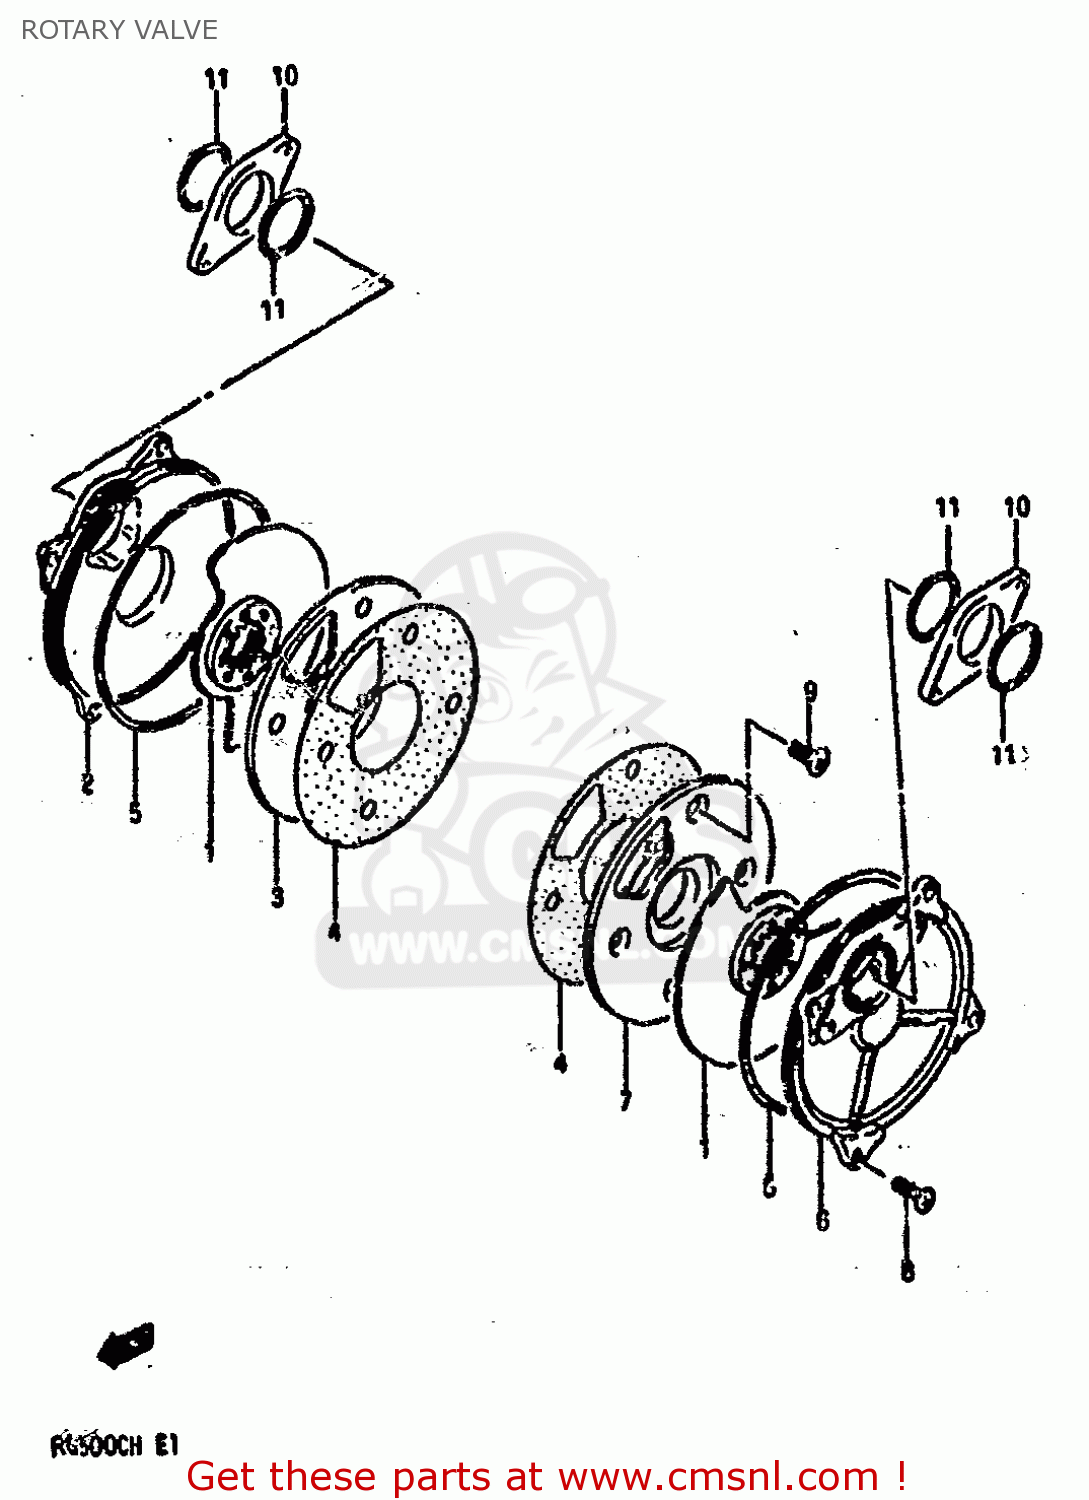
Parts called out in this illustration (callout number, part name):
1	PLATE,CRANKSHAFT VALVE
2	SEAT,OUTER VALVE,R
3	SEAT,INNER VALVE,R
4	GASKET,VALVE SEAT (NAS)
5	O RING(D:1.9,ID:113)
6	SEAT,OUTER VALVE LH
7	SEAT,INNER VALVE,L
8	SCREW
9	SCREW
10	INSULATOR,CARBURETOR
11	O RING(D:1.9,ID:32.7)
